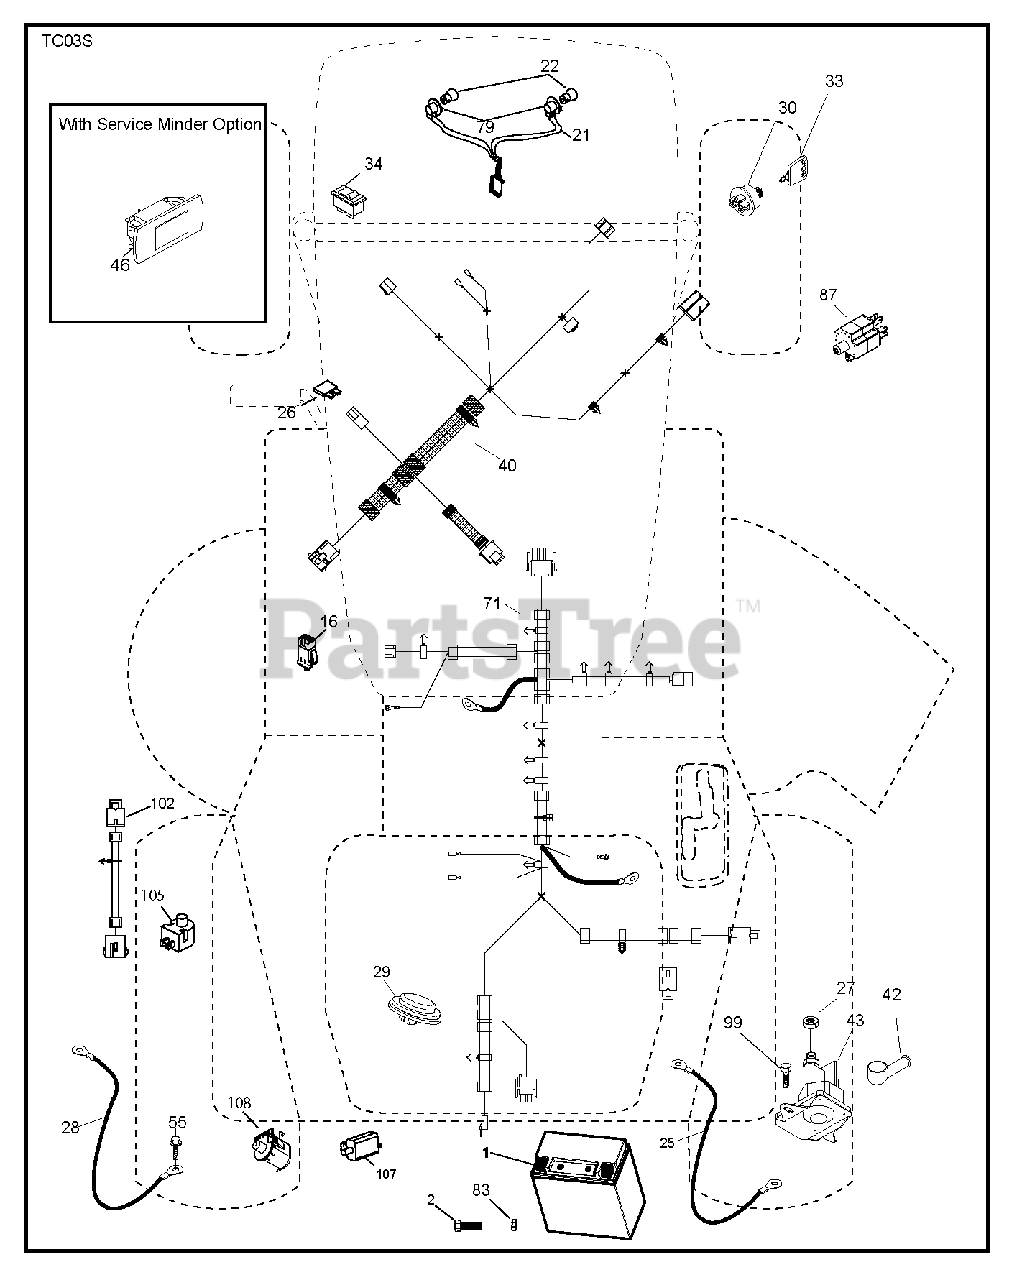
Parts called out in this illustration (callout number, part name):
1	BATTERY BATTERY 14AH 12V LEOC
2	SCREW.HEX.HEAD.CAP.M6 X1.12W
16	SWITCH INTERLOOK PUSH-IN
21	HARNESS.LIGHT W/4152J BULBS
25	CABLE BATTERY CABLE
26	FUSE 20AMP
27	NUT
29	SWITCH.SEAT.DELTA.OPC.
30	SWITCH.IGN.DELTA.W.LGH.ROS
33	KEY.CHAIN.BLISTER.PACK.GEN.INT
40	RP HARNESS.ELECTRICAL.DASH.SRD
42	TERMINAL COVER
43	SOLENOID.W/BRASS.PLUNGER
46	RP GUAGE.SRVCMNDR.HRMTR.
55	SCREW 5/16"
71	HARNESS-CHASSIS SUB
79	BULB HOLDER ASM.
83	NUT NUT SQUARE
87	RP SWITCH.RAILMOUNT.NO-NC-NC
99	SCREW
102	HARNESS PIGTAIL PCH TEX ROS
105	REVERSE SWITCH
107	.WITCH.FULL BAGGER.INDICATOR
108	SWITCH.SNAPMOUNT.NC
